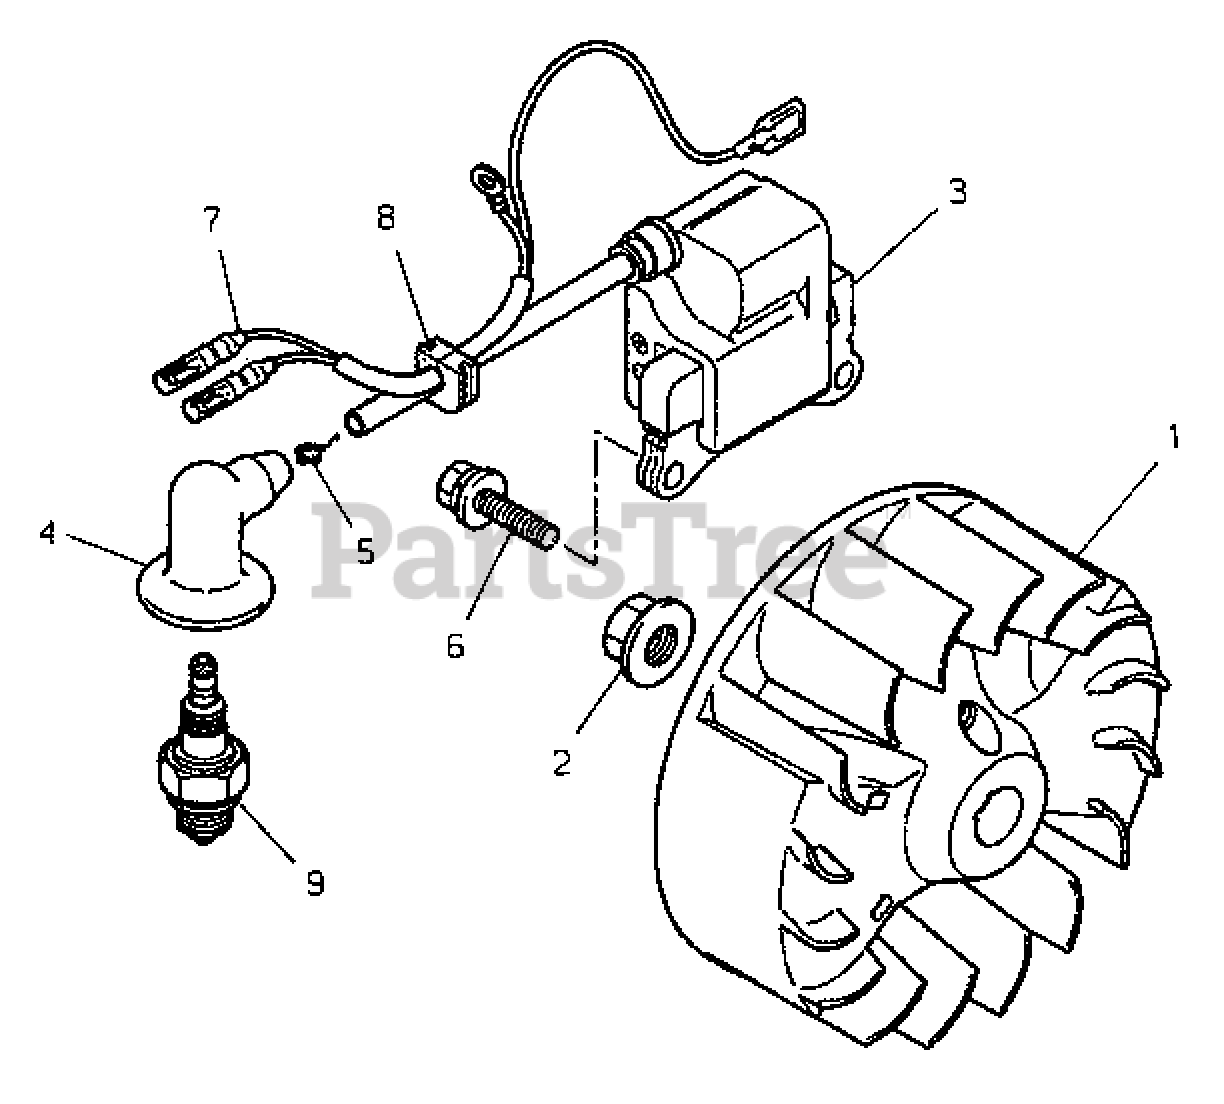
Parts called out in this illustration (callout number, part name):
1	ROTOR
3	IGNITION COIL ASSY
4	CAP, SPARK PLUG
5	SPRING, PLUG
7	LEAD WIRE
9	SPARK PLUG - BPMR-8Y
